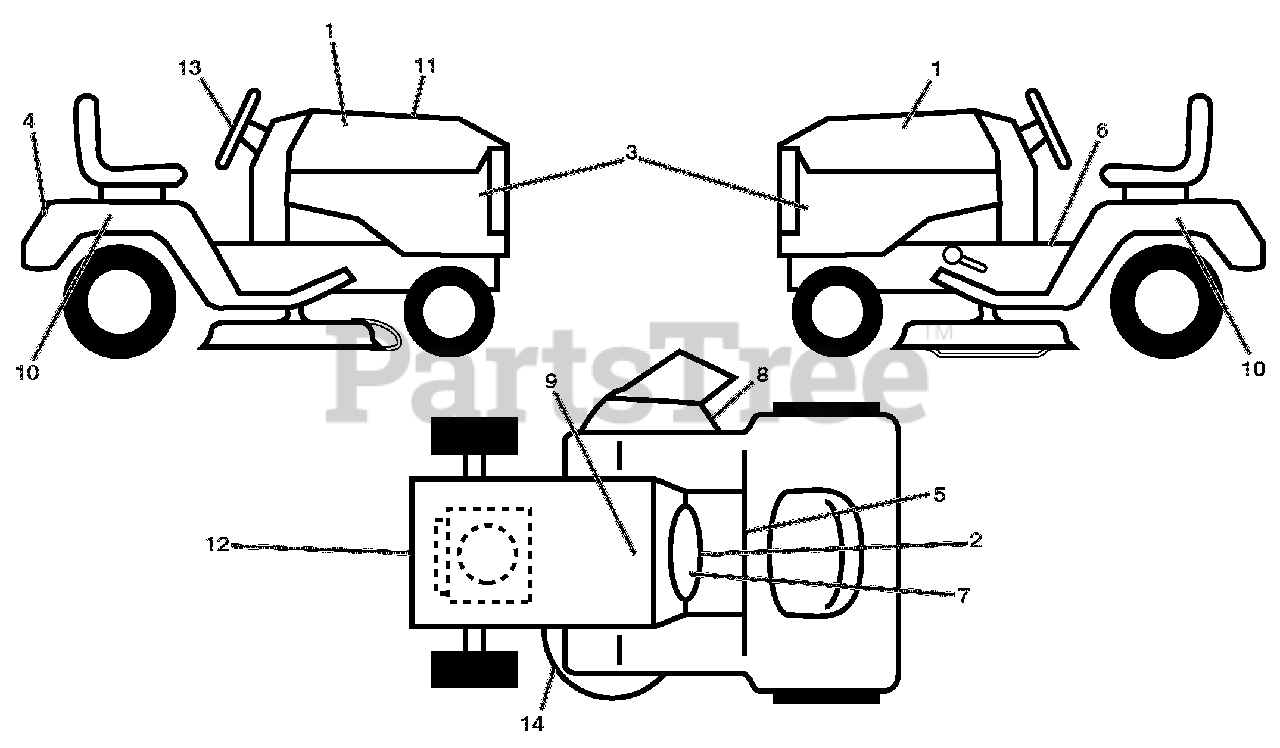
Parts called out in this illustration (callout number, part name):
1	DECAL.HOOD.RH.PRECISION.ARIENS
2	Decal, Spark Arrester
3	DECAL.SDPNL.PWRDBY KOHL.ARIENS
4	DECAL.FENDER.REAR.ARIENS
5	DECAL.FENDER
6	DECAL, WARNING START INST.
7	LABEL EMISSION
8	DECAL.MOWER.WARN.KEEP HAND AWY
9	DECAL.BAT.DAN/POI P/L SYM.WPN
10	DECAL.FENDER.SIDE.HYDRO.ARIENS
11	DECAL REPLACEMENT
12	DECAL ENGINE
13	DECAL.WHEEL.STEER.ARIENS
14	DECAL.V-BELT.SCH.42/46"MEC/ELE
